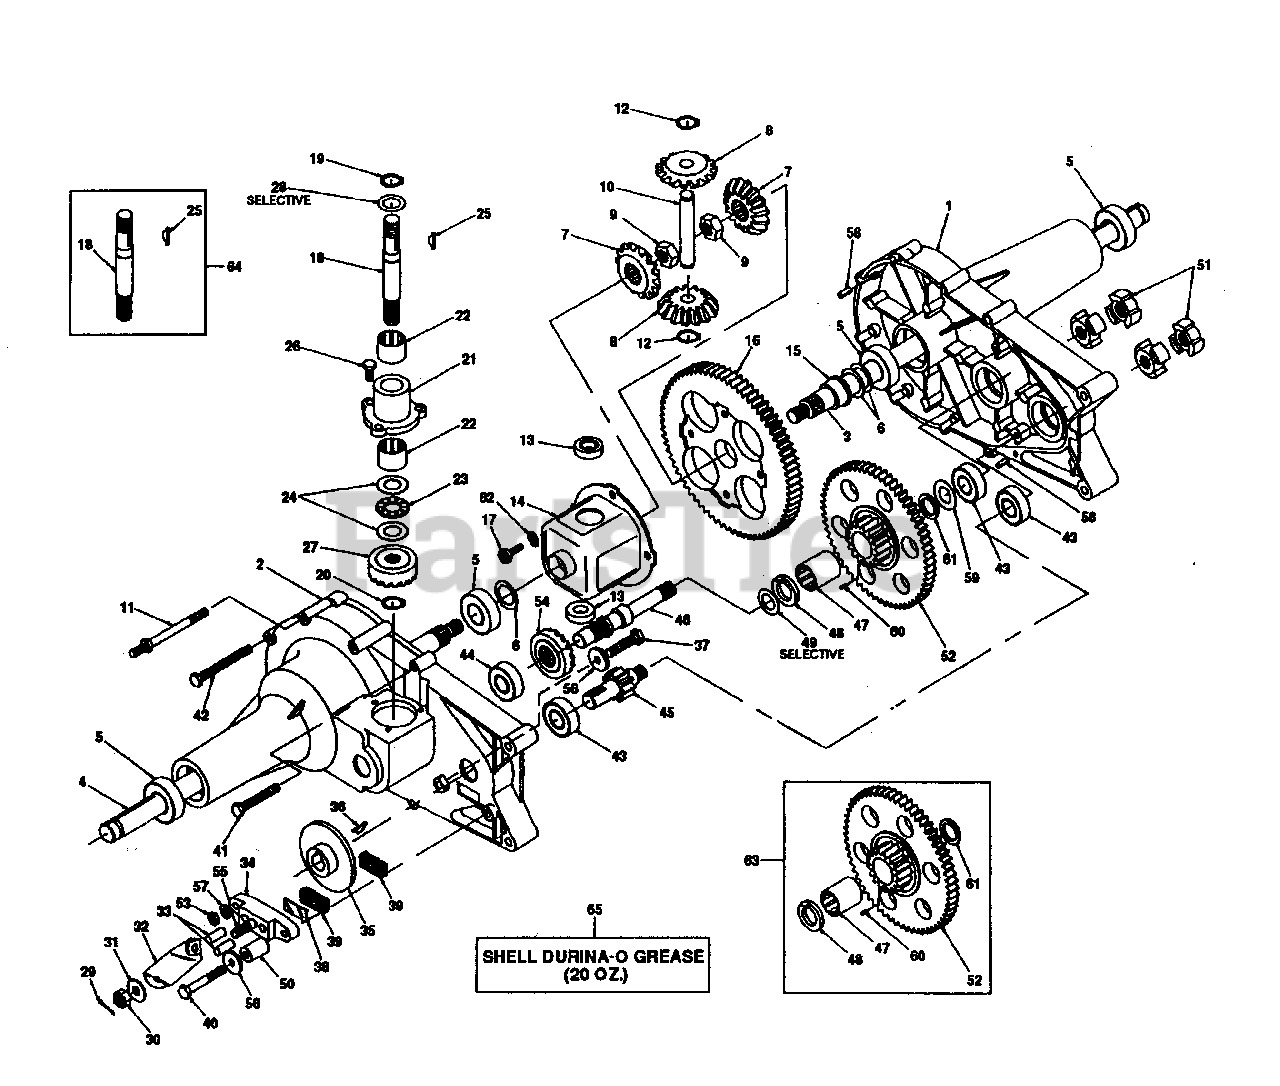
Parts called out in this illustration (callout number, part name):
1	Housing, Half L.H.
2	Housing, Half R.H.
5	Bearing, Ball
6	Washer, Flat 3/4 x 1-1/8 x .030
7	Gear, Miter
8	Gear, Miter
9	Nut, Hex Jam w/Patch 1/2-20
11	Screw, Stud
13	Bearing, Thrust
14	Housing Assembly, Differential
15	Bearing, Flange
16	Gear, Differential 72 Tooth
17	Bolt, Torx Head 1/4-28 x 5/8"
18	Shaft, Input
20	Retaining Ring 7/16"
21	Housing, Input Bearing
22	Bearing, Needle
23	Bearing, Thrust
24	Washer, Flat 5/8 x 1-1/8 x .030
25	Key, Hi-Pro 3/32 x 5/8
26	Screw, Hex W/Patch 1/4-20 x 3/4
27	Gear, Input Pinion 17 Tooth
28	Washer, Flat .62 x 1 x .05
30	Nut, Castle 5/16-24
31	Washer, Flat .343 x .88 x .062
32	Arm, Brake Actuator
33	Pin, Brake Actuating
34	Brake, Yoke
36	Key, Hi-Pro 3/16 x 5/8"
37	Screw, Hex 1/4-20 x 1.50
39	Puck, Brake
40	Screw, Hex w/Patch 1/4-20 x 2.00
41	Screw, Hex Self-Tap 1/4-20 x 2.00
42	Screw, Hex Self-Tap 1/4-20 x 3.00
43	Bearing, Ball
44	Bearing, Ball
45	Shaft, Pinion W/11 Tooth Gear
47	Bearing, Needle
48	Bronze Thrust Brg. 5/8 x 1-1/4 x 7/64
49	Washer, Flat .62 x 1.0 x .050
52	Gear, 60 and 17 Tooth
53	Nut, Hex 1/4-20
54	Gear, Drive Pinion 17 Tooth
55	Bolt, Square Head
56	Washer 15/16 x .265 x .125
57	Washer, Spring Lock 1/4"
58	Pin, Roll 3/16" x 1/2"
59	Washer, Flat .62 x 1.0 x .030
60	Pin, Dowel 3/32 x 1/4
62	Washer, Head Spring Lock 1/4"
63	Assembly, Gear, Reduction
64	Assembly, Shaft, Input
65	Shell Durina-O Grease (20 oz.)
